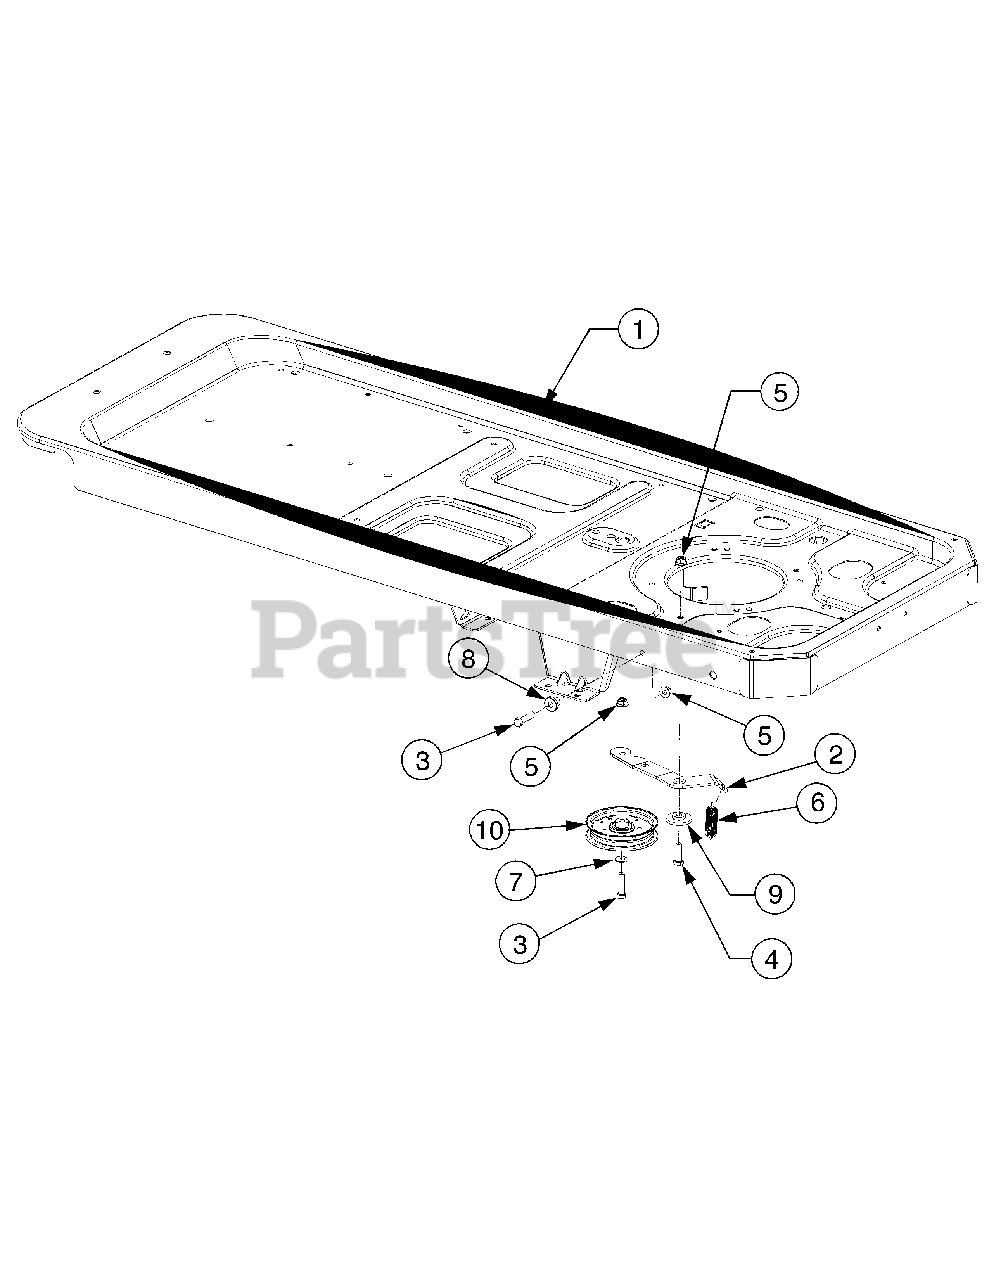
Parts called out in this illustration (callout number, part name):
3	Screw, Hex Cap, 3/8-16 x 1.5 GR5
4	Screw, Hex Cap, 3/8-16 x 1.25 GR5
5	Nut, Hx Insert Flnge Lck, 3/-16 GrF
6	Spring, Extension, .75 x 5.06
7	Washer, Flat, .408 x .875 x .059
8	Spacer, Shoulder, .39 x 1.0 x .7
9	Spacer, Shoulder, .884 x .19
10	Pulley, Idler, 4.25 Dia.
